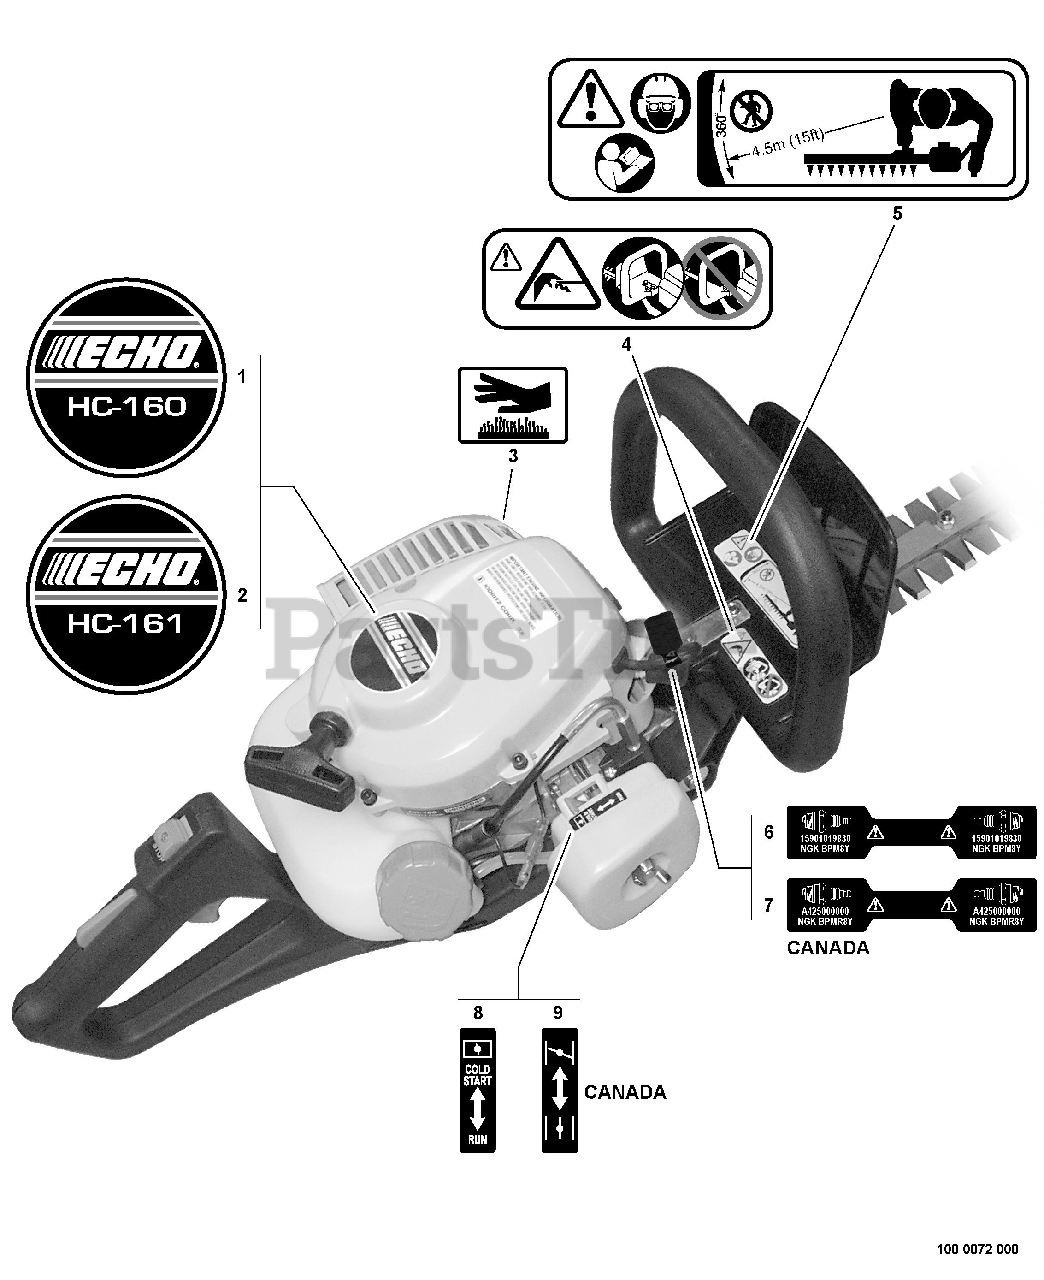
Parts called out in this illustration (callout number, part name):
1	LABEL - MODEL HC-160
2	LABEL - MODEL HC-161
3	LABEL - HOT SURFACE
4	LABEL - CAUTION
5	LABEL - CAUTION
6	LABEL - SPARK PLUG -- BPM-8Y
7	LABEL - SPARK PLUG -- BPMR-8Y
8	LABEL - CHOKE
9	LABEL - CHOKE
